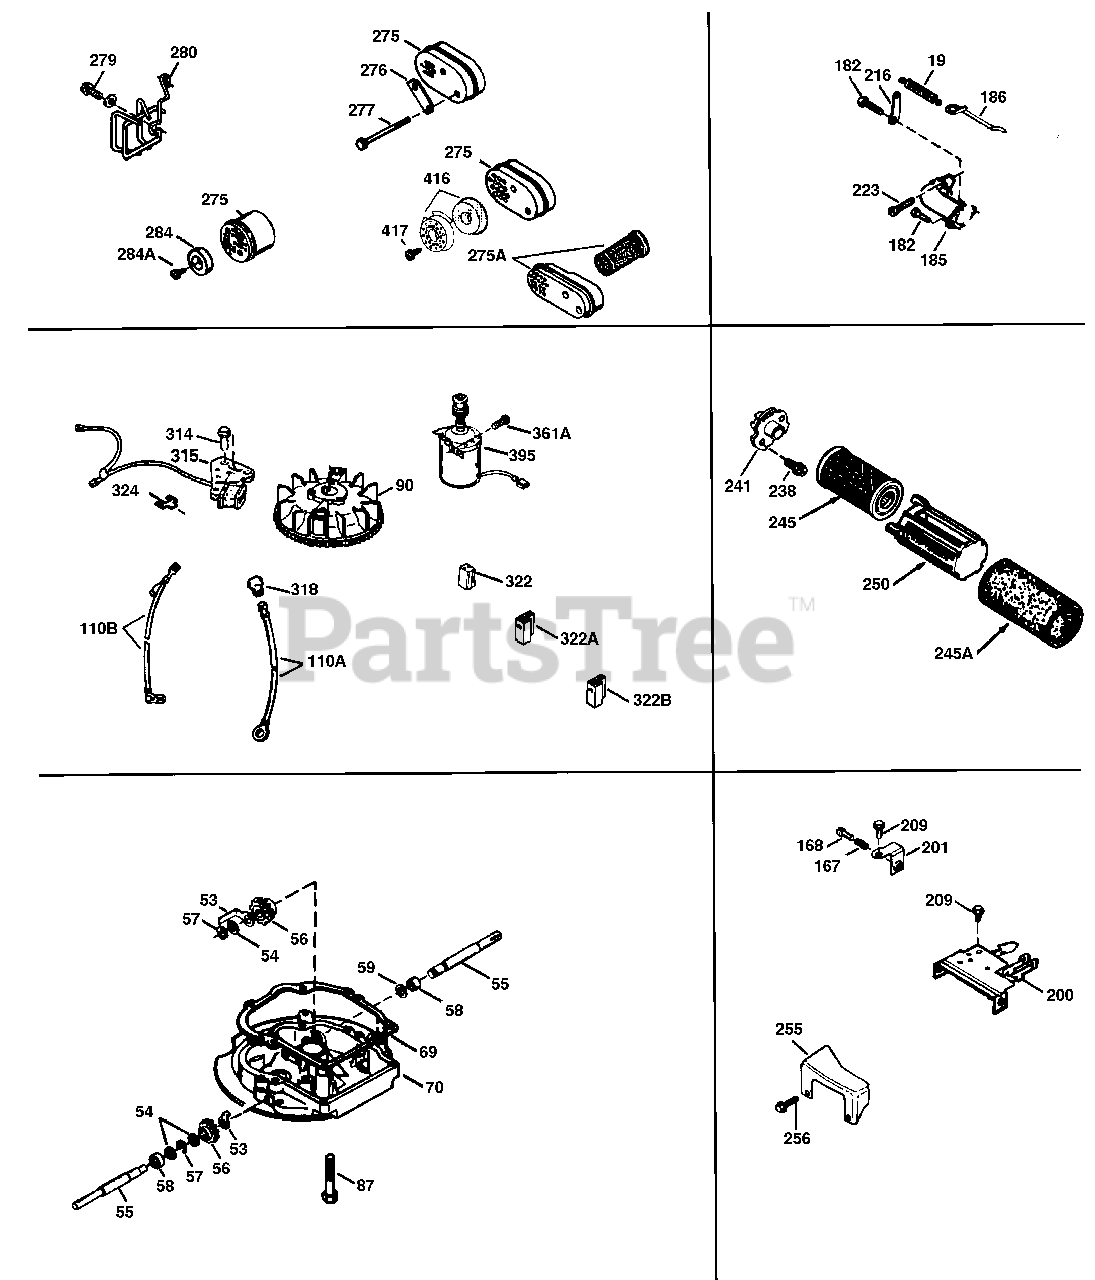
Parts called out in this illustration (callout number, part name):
19	Throttle Spring
69	* Mounting Flange Gasket
70	Mounting Flange (Incl.72 thru 83,306)
90	Flywheel
182	Screw, 1/4-28 x 7/8"
185	Intake Pipe
186	Governor Link
200	Control Bracket (Incl. 202 thru 205)
209	Screw, 10-24 x 9/16"
223	Screw, 1/4-20 x 1"
238	Screw, 10-32 x 49/64"
241	Air Filter Collar
245	Air Filter (Paper) (also available in Packaged Part #740095 (Qty.2))
250	Air Cleaner Cover
275	Muffler (Incl. 277)
275A	Spark Arrestor Muffler (Optional)(Inc l. 284,284A,416 & 417)
277	Screw, 1/4-20 x 2-5/16"
279	Screw, T-30, 1/4-20 x 1/2"
280	Heat Shield
284	Muffler Deflector (Incl. 284A) Option al
284A	Screw, 10-32 x 1/2" (Optional)
416	Spark Arrestor Kit (Incl. 417) Option al
417	Screw, 10-32 x 1/2" (Optional)
999	Summer Maintenance Kit (incl. Oil, Sp ark Plug, Air Cleaners (2), & Ultra-F resh)
